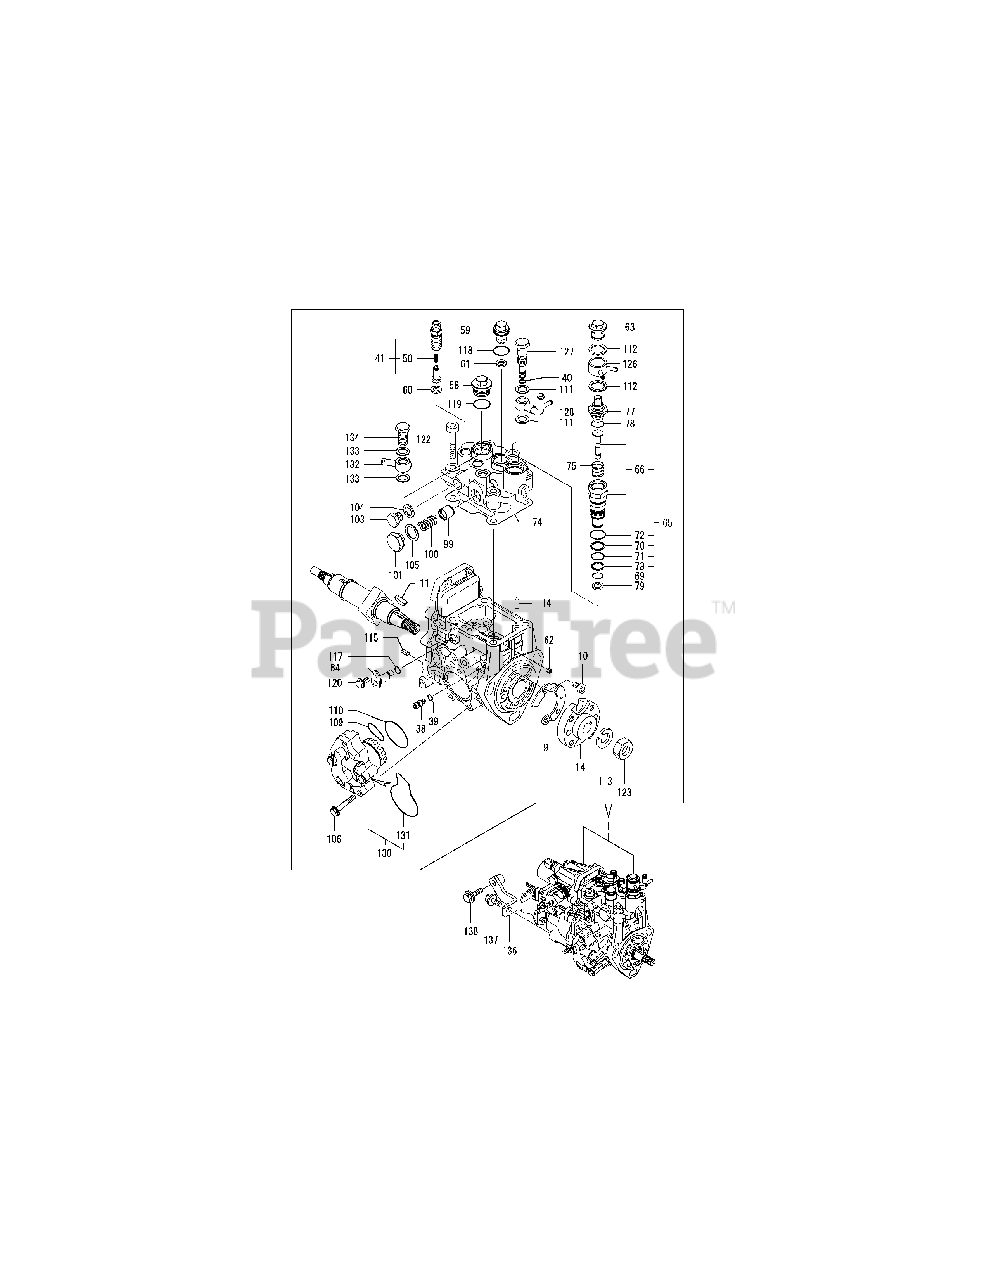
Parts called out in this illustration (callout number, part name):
1	INJECTION PUMP ASSY
11	KEY, WOODRUFF 4X16
38	STOPPER, TAPPET
41	SETTING, DELIVERY
50	SPRING, DELIVERY
60	PK(BARREL PLUG
61	PK(BARREL PLUG
63	PLUG, WATER PUMP
72	PACKING, 19020
73	RING, BACKUP T2 P 15
77	ELEMENT, THERMO
100	SPRING, ACTUATOR
104	SEAL WASHER 12
111	SEAL WASHER 12
113	SPRING WASHER 14
114	PARALLEL PIN 5X14
115	SPRING PIN 5X10
117	O-RING 1A P-7.0
118	O-RING 4D 19018
119	PACKING, 19020
120	BOLT 6X 10 PLATED
123	LOCK NUT M14 PLATED
126	JOINT, COOLING WATER
127	JOINT, OVER FLOW
128	JOINT, OVER FLOW
130	PUMP ASSY, FUEL FEED
132	JOINT, PIPE 12
133	SEAL WASHER 12
134	JOINT BOLT 6,PIPE
136	RETAINER, PUMP
137	BOLT M 8X 20 PLATED
138	BOLT M 8X 30 PLATED
